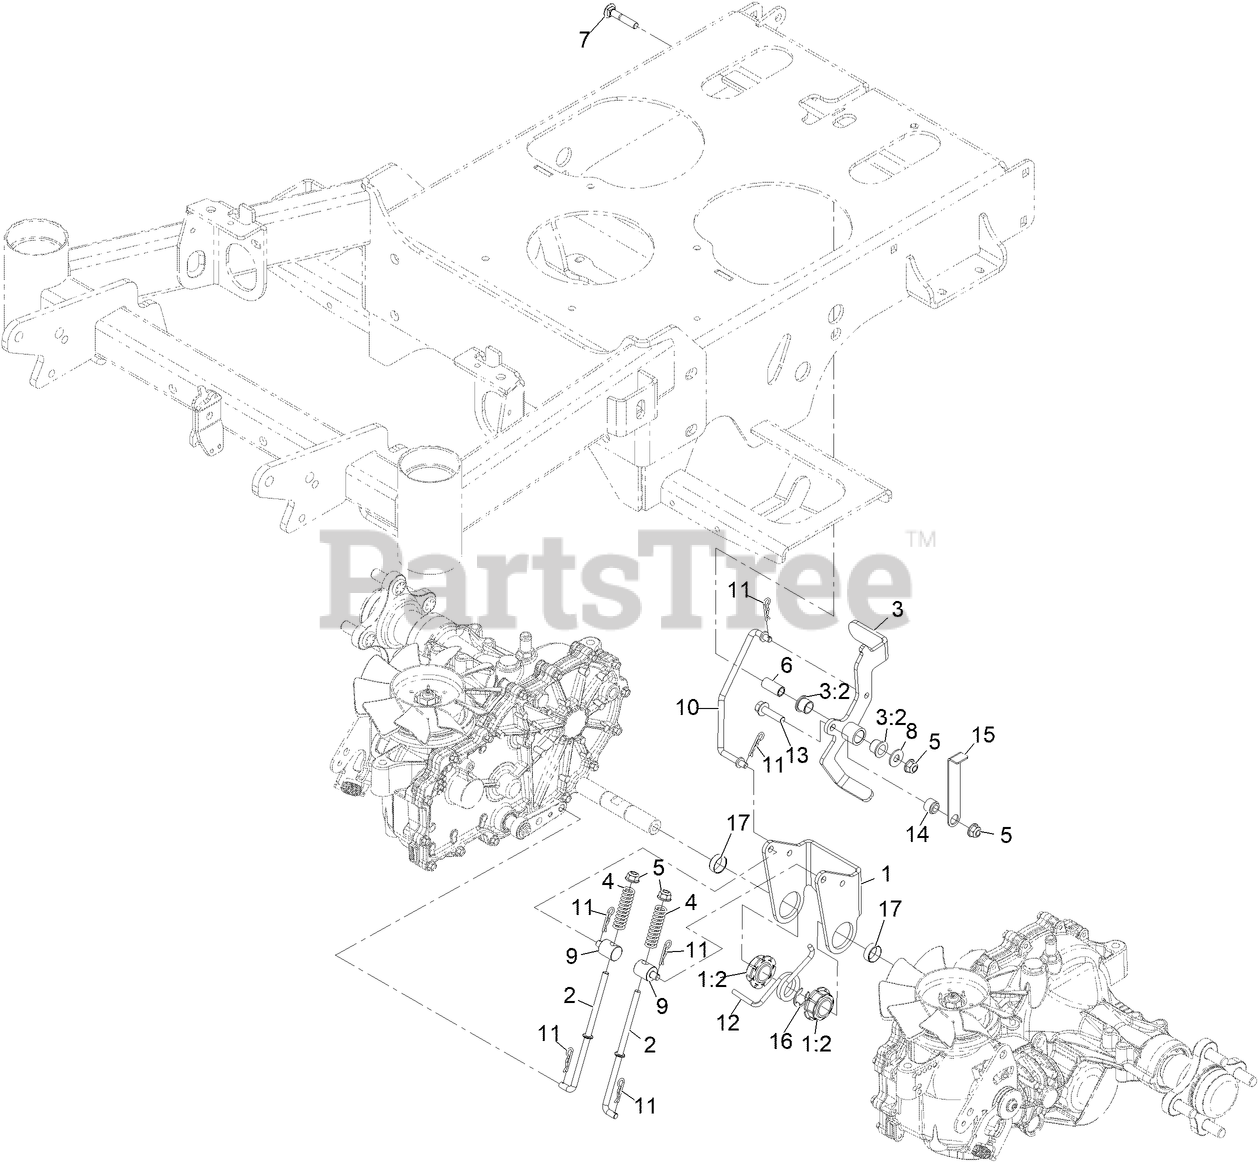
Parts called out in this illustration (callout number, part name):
1	ASM-BRAKE, BELL CRANK
1:2	BEARING-SPHERICAL
2	ROD-BRAKE, LOWER
3	ASM-BRAKE, HANDLE
3:2	BEARING-FLANGE
4	SPRING-COMPRESSION
5	Nut-Hex Flange
6	SPACER-BRAKE
7	Screw-CARR
8	FLAT WASHER, 5/16 NOM,ST
9	FITTING-ROD
10	ROD-BRAKE, UPPER
11	PIN-COTTER
12	SPRING-TORSION
13	SCREW-HHF
14	SPACER-BRAKE, INTERLOCK
15	PLATE-BRAKE, INTERLOCK
16	RETAINER, E-RING
17	BUSHING-SLEEVE
